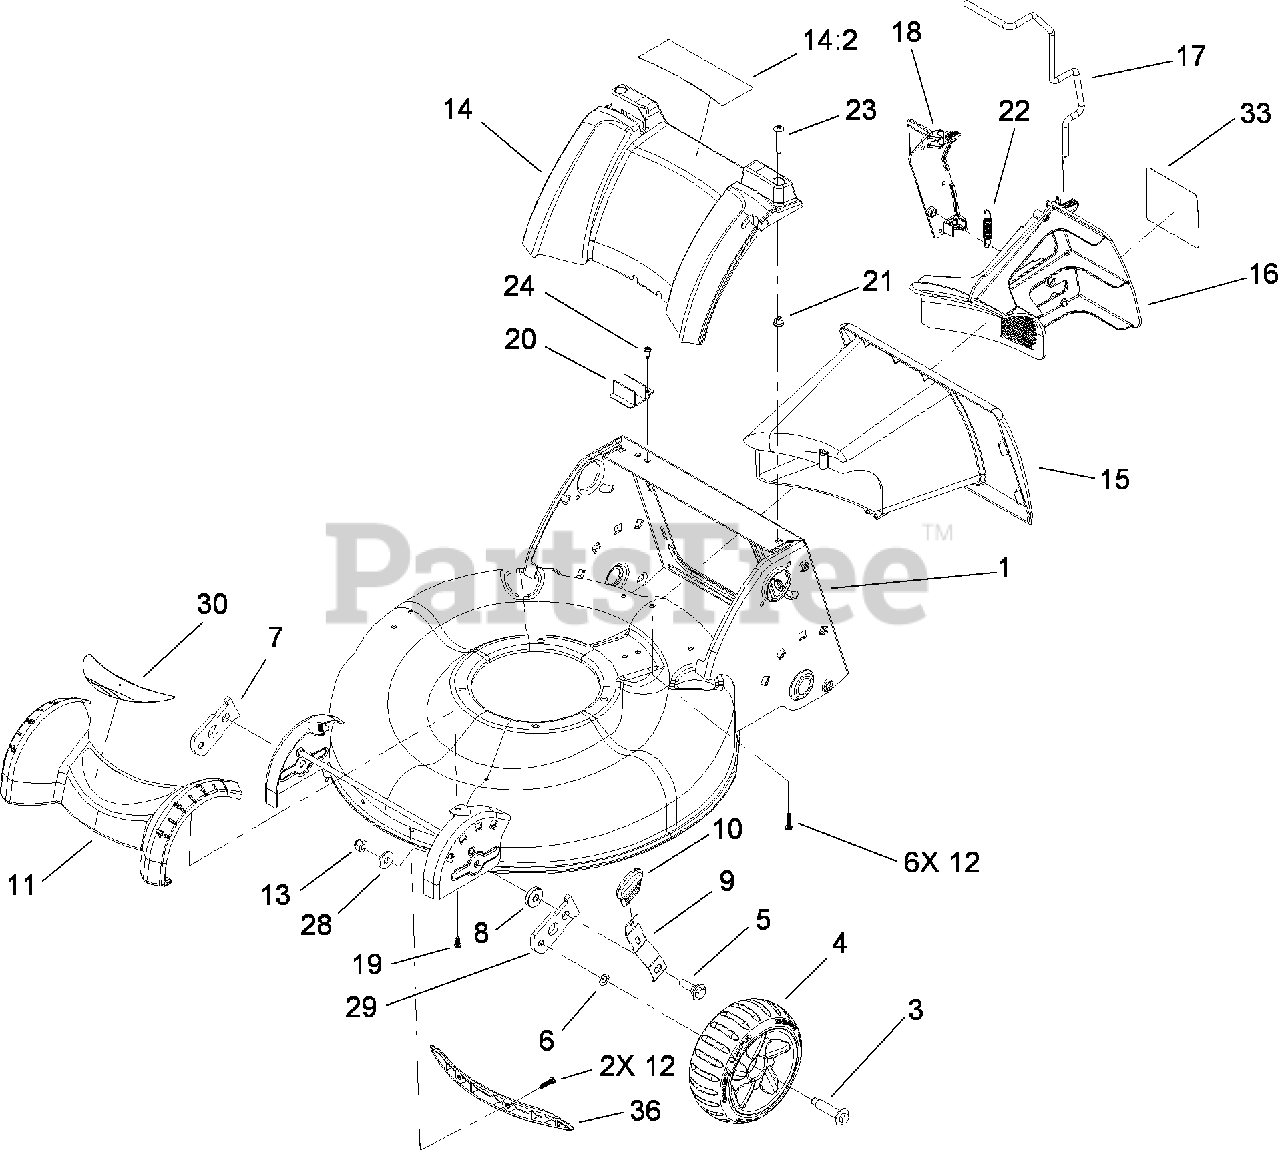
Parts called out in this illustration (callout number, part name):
1	HOUSING ASM
3	BOLT-SHOULDER
4	7 INCH FRONT WHEEL ASM
5	BOLT-SHOULDER
7	ARM-PIVOT, RH
9	ARM-SPRING
11	COVER-FRONT
12	SCREW-PLASTITE
13	NUT-LOCK, NI
14	COVER-REAR
14:2	DECAL-WARNING
16	PLUG-MULCH, LH
17	LATCH-MULCH PLUG
18	PLUG-MULCH, RH
19	SCREW-PLASTITE
20	MODULE-SWITCH
21	NUT-CLIP
22	SPRING-EXTENSION
23	SCREW-PTH
24	SCREW-THREAD FORMING
28	WASHER-HARDENED
29	ARM-PIVOT, LH
33	DECAL-MULCH PLUG
36	INSERT-HOUSING
